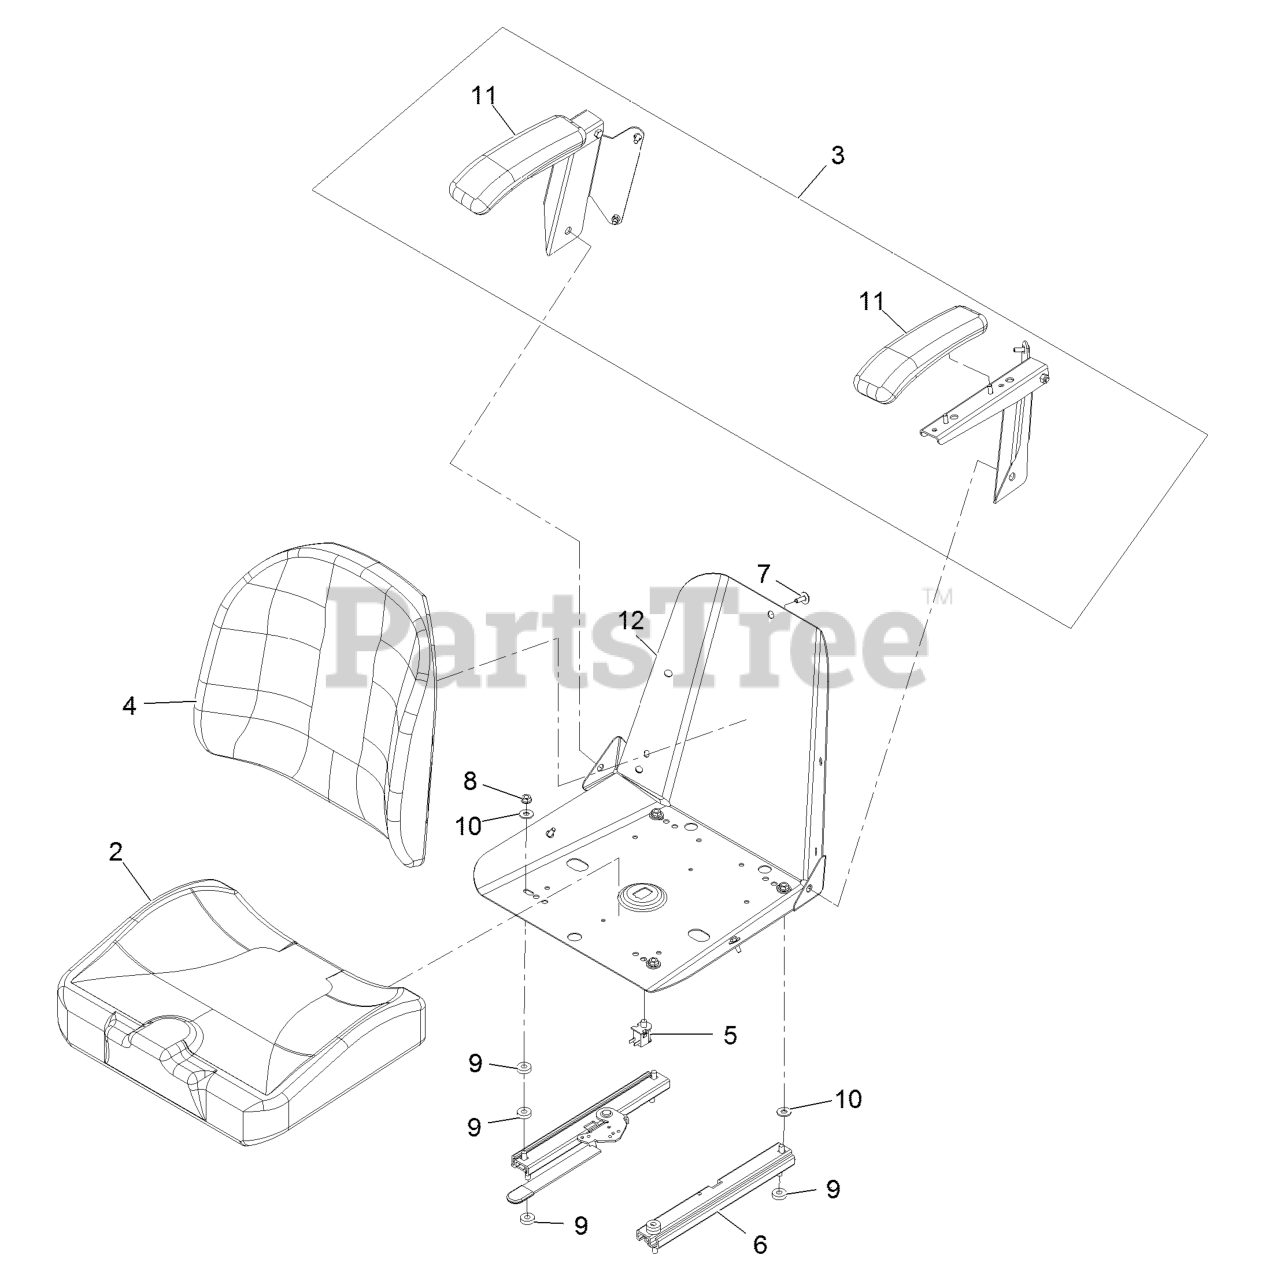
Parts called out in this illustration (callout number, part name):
2	CUSHION-SEAT BOTTOM
3	ARMREST KIT
4	CUSHION,SEAT BACK
5	SWITCH-BAIL
6	TRACK-SEAT
7	BOLT-SEAT
10	WASHER-FLAT
11	CUSHION-REST, ARM
12	FRAME-SEAT
